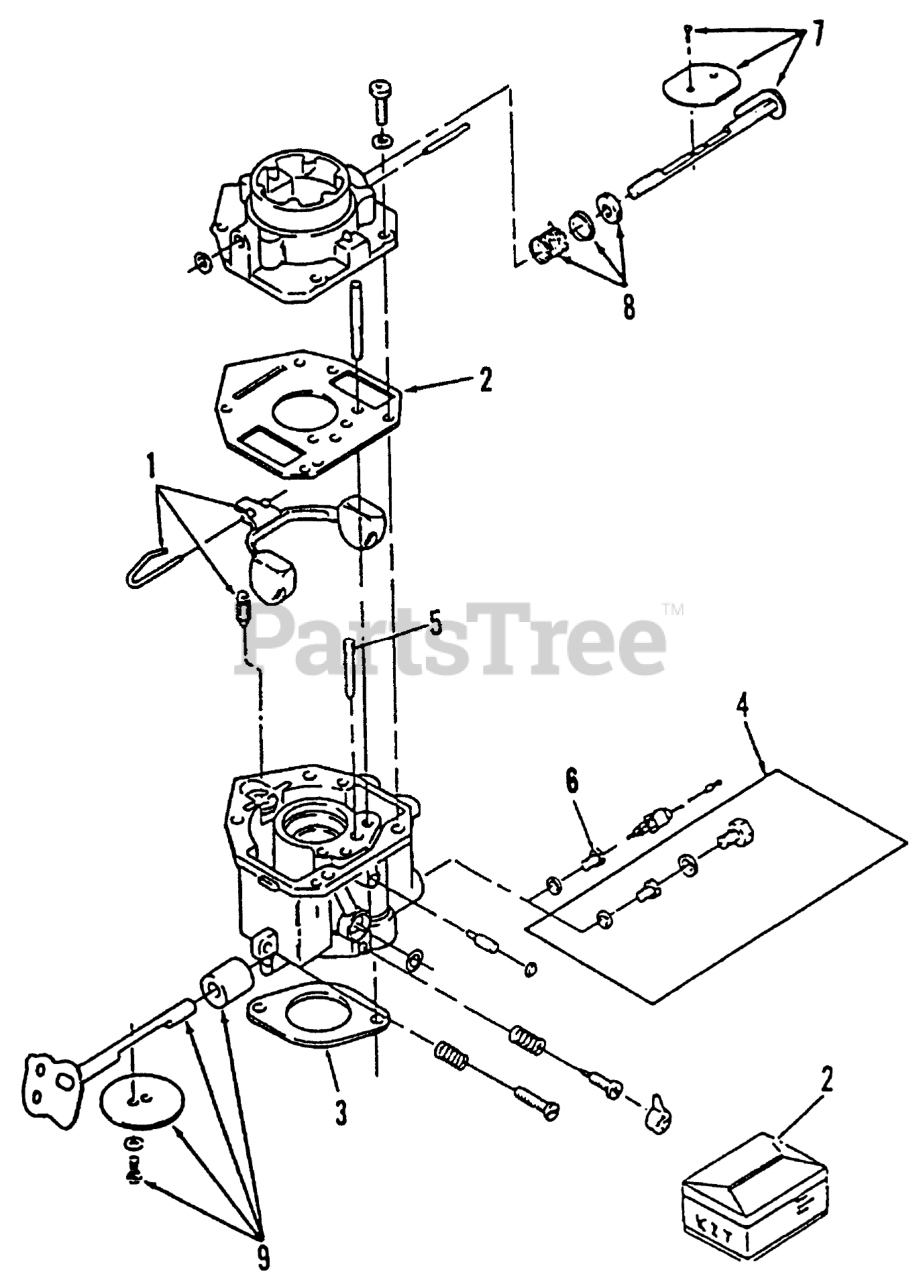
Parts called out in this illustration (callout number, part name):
1	Kit-Float (Includes Float, Pin, & Valve)
2	Kit-Repair (Includes Screw & Plug Package, Gasket Package, Float Valve, Idle Adjustment Needle & Spring, Mounting Gaskets, & Idle Limit Cap)
3	GASKET-CARBURETOR
4	FIXED-JET PKG
5	Idle Jet
6	POWER JET
7	Kit-Choke Shaft (Includes Choke Valve, Valve Screw-Set, & Air Filter)
8	Kit-Choke Lever (Include Choke Lever Ring, Choke Spring, & Choke Collar)
9	Kit-Throttle Shaft (Includes Valve Screw-Set, Air Filter, & Throttle Valve)
